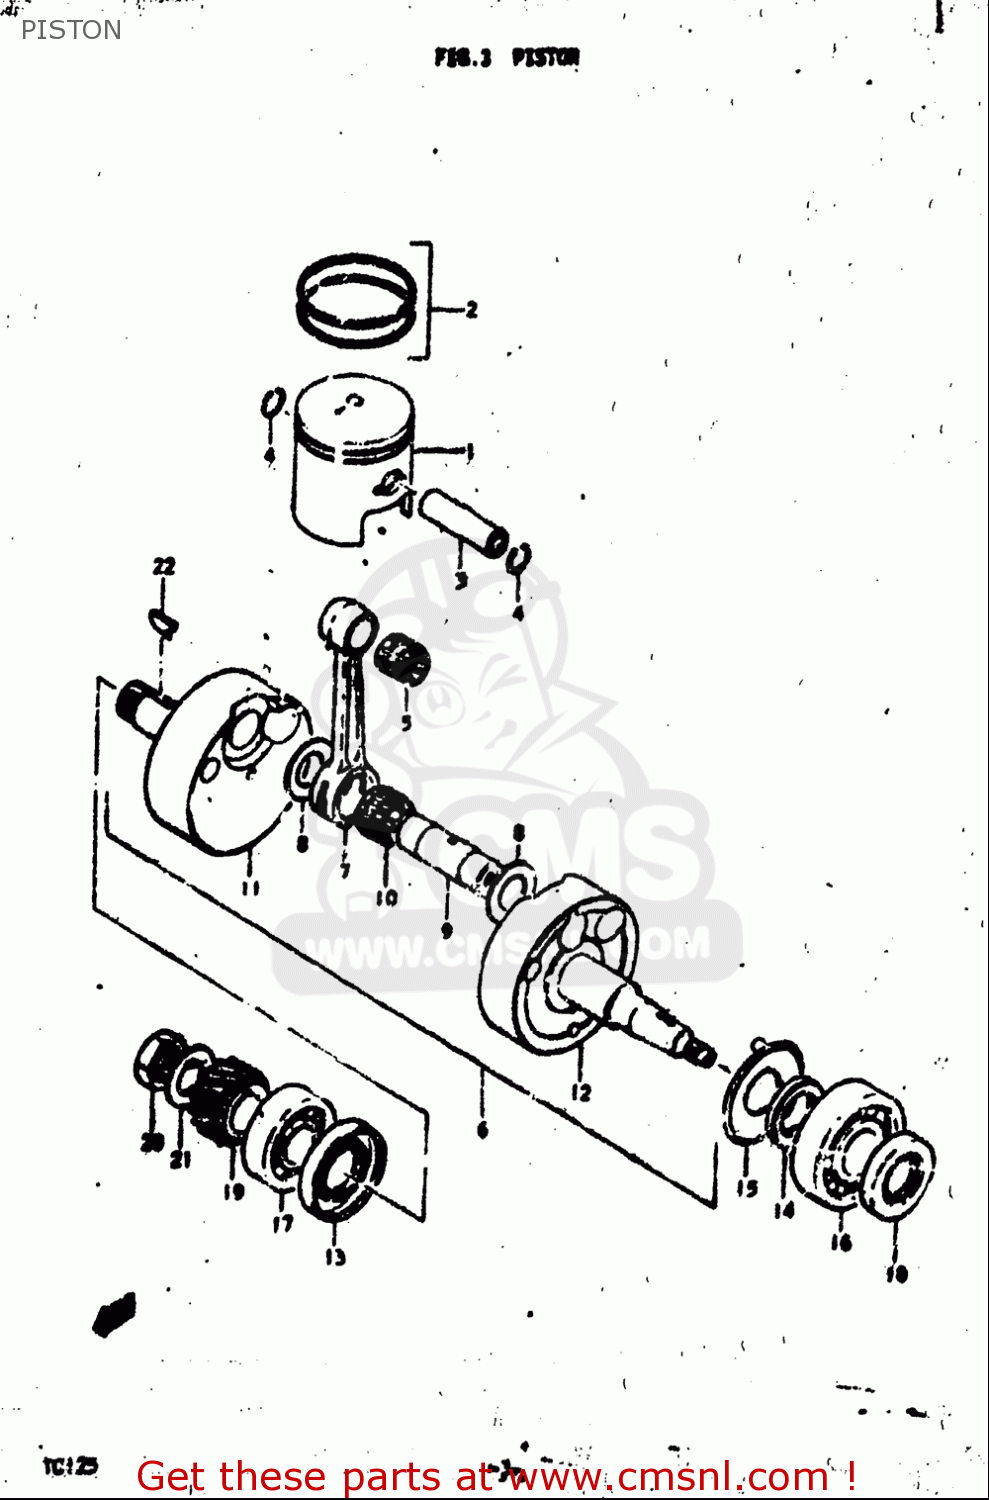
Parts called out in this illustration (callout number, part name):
1	PISTON
2	RING SET,PISTON
3	PIN ,PISTON
4	RING,SNAP 14MM
5	BEARING(14X18X19.8)
7	ROD,CONNECTING
8	WASHER(19X32X1)
9	PIN,CRANK
10	BEARING(19X25X16)
13	SEAL,OIL(26X52X8)
14	SPACER
16	BEARING(25X62X17)
17	BEARING(20X52X15)
18	SEAL,OIL(25X44X7)
20	NUT
21	WASHER
22	KEY
